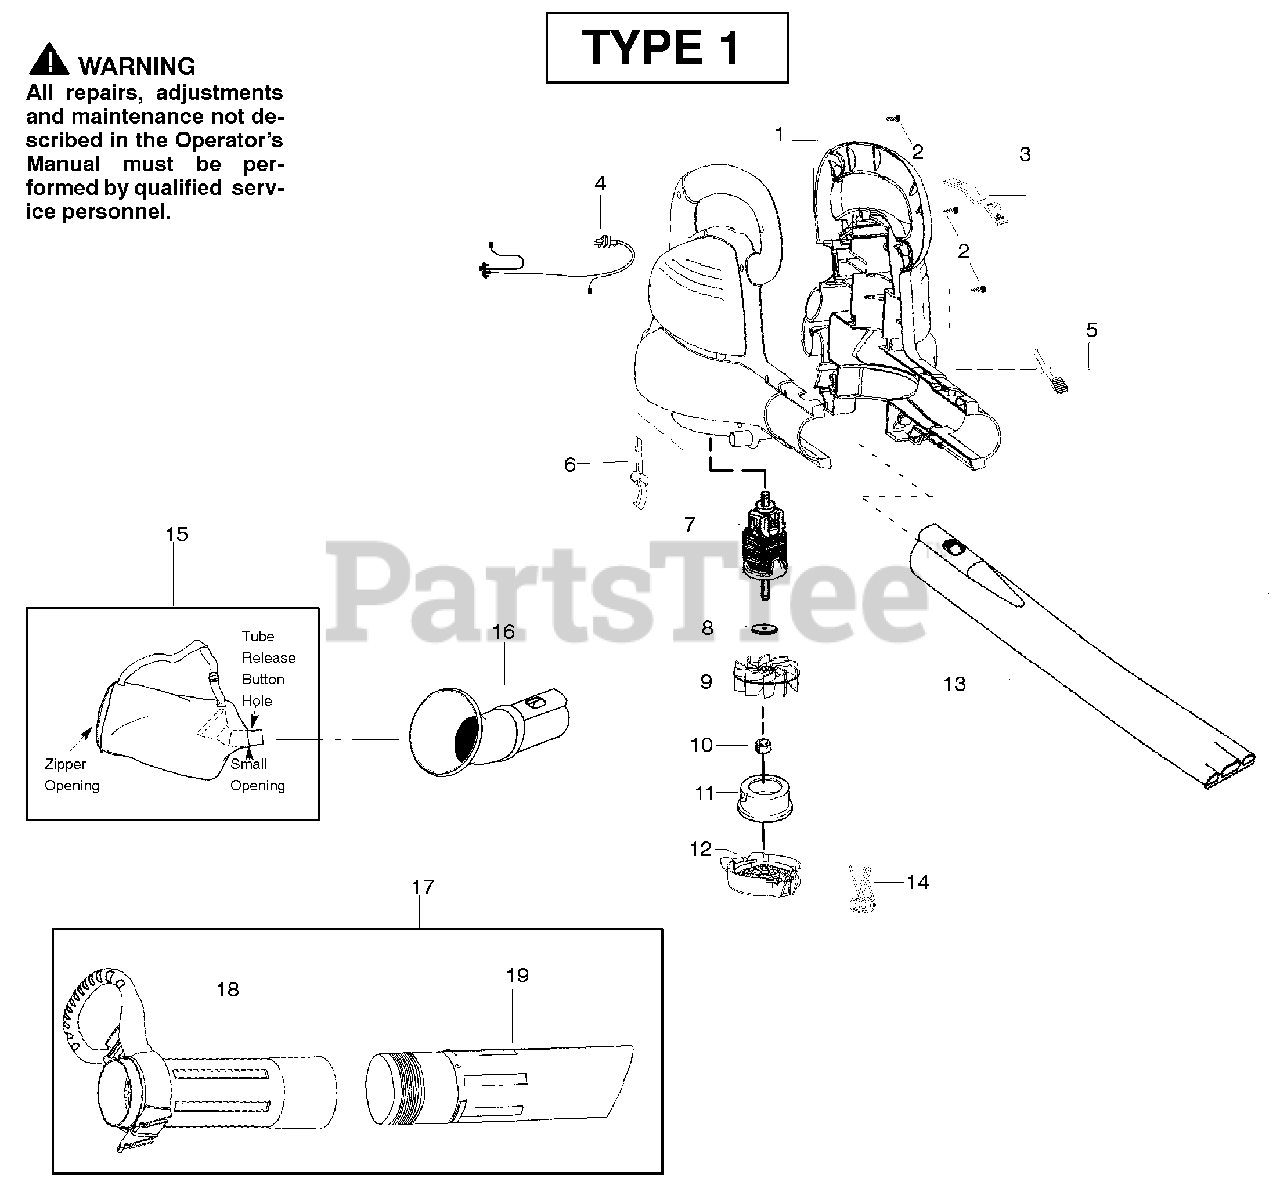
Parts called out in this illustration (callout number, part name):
1	Housing Set
3	Cover - Switch
4	Assy. Wiring Harness
5	Button - Tube Latch
6	Button - Door Latch
7	Assy. Motor
9	Impeller
10	Nut - Impeller
11	Restrictor - Inlet
12	Door - Vacuum Inlet
13	Tube - Blower
14	Spring - Door
15	Assy. - Vac Bag
16	Tube - Elbow
17	Kit-Upper/Lower Tube w/handle
18	Tube - Upper Vac w/handle
19	Tube - Lower Vac
